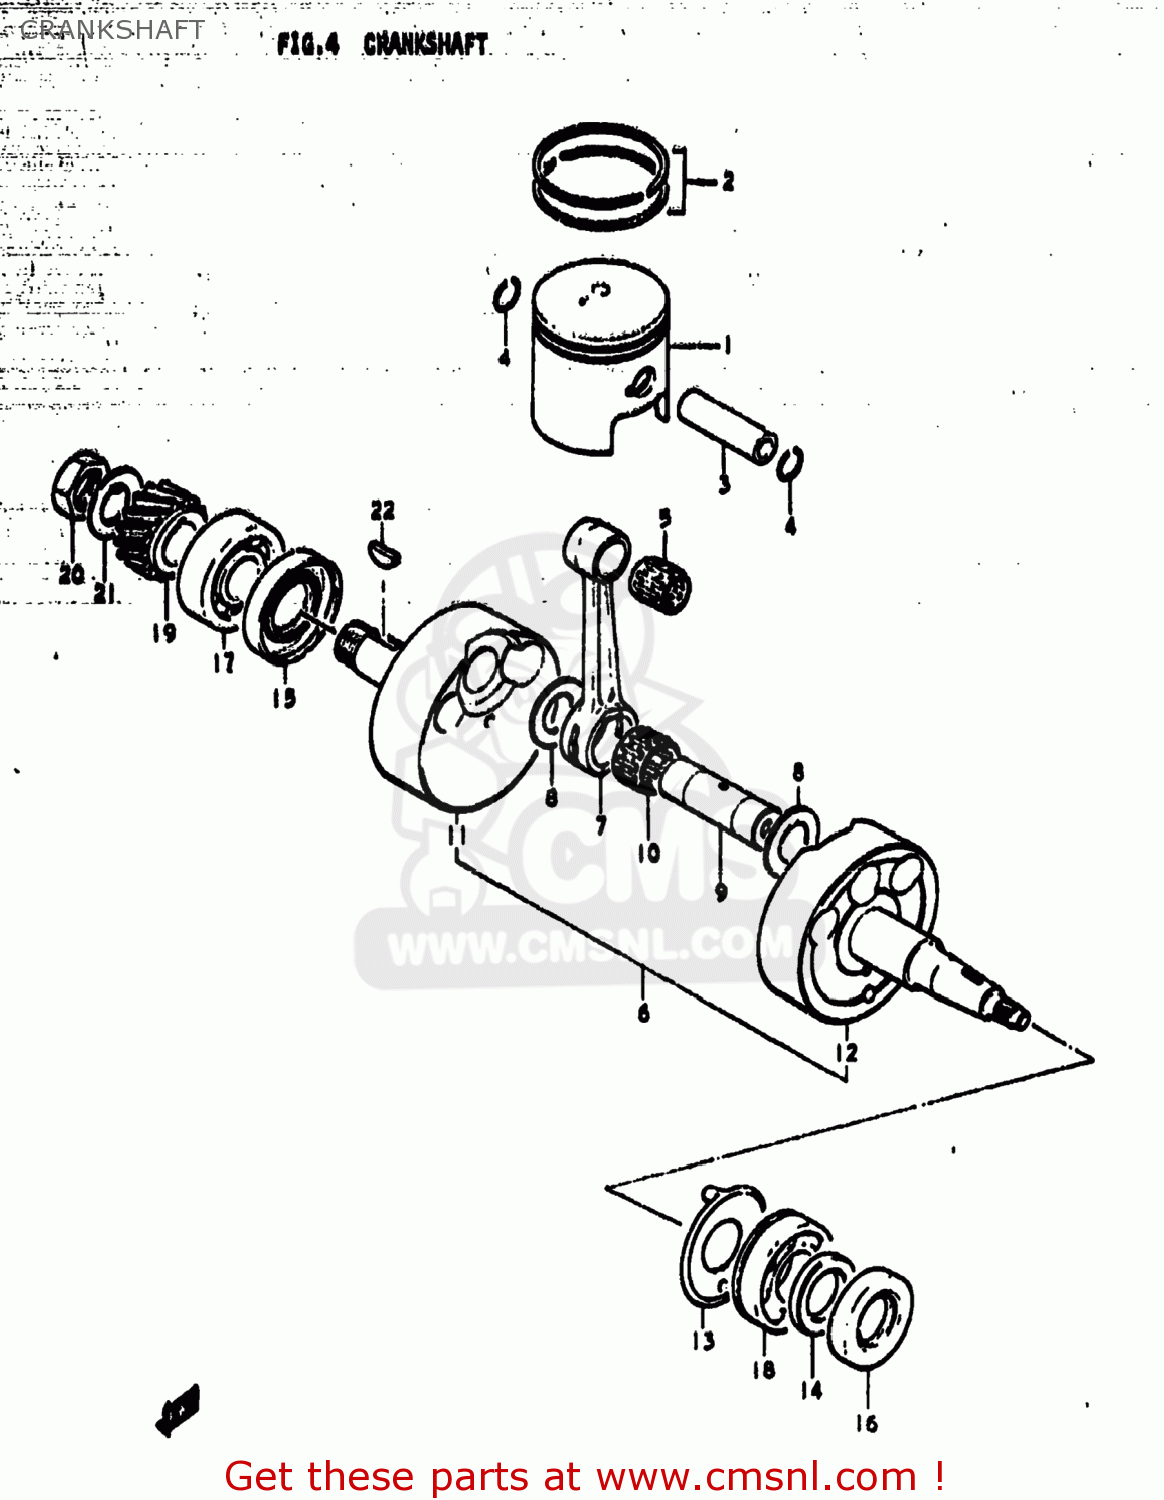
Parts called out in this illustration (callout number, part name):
1	PISTON
2	RING SET,PISTON
3	PIN,PISTON
4	RING,SNAP 16MM
5	BEARING
6	CRANKSHAFT ASSEMBLY
7	ROD, CONNECTING
8	WASHER(22X35X1)
9	PIN,CRANK
10	BEARING 22X28X16
11	CRANKSHAFT,R
12	CRANKSHAFT,LEFT
13	PLATE,CSHAFT OIL GUIDE
14	SPACER(25X34X4.5)
15	SEAL,OIL(26X52X8)
16	OIL SEAL
17	BEARING
18	BEARING(25X62X17)
19	GEAR,PRIMARY DRIVE
20	NUT
21	WASHER
22	KEY
